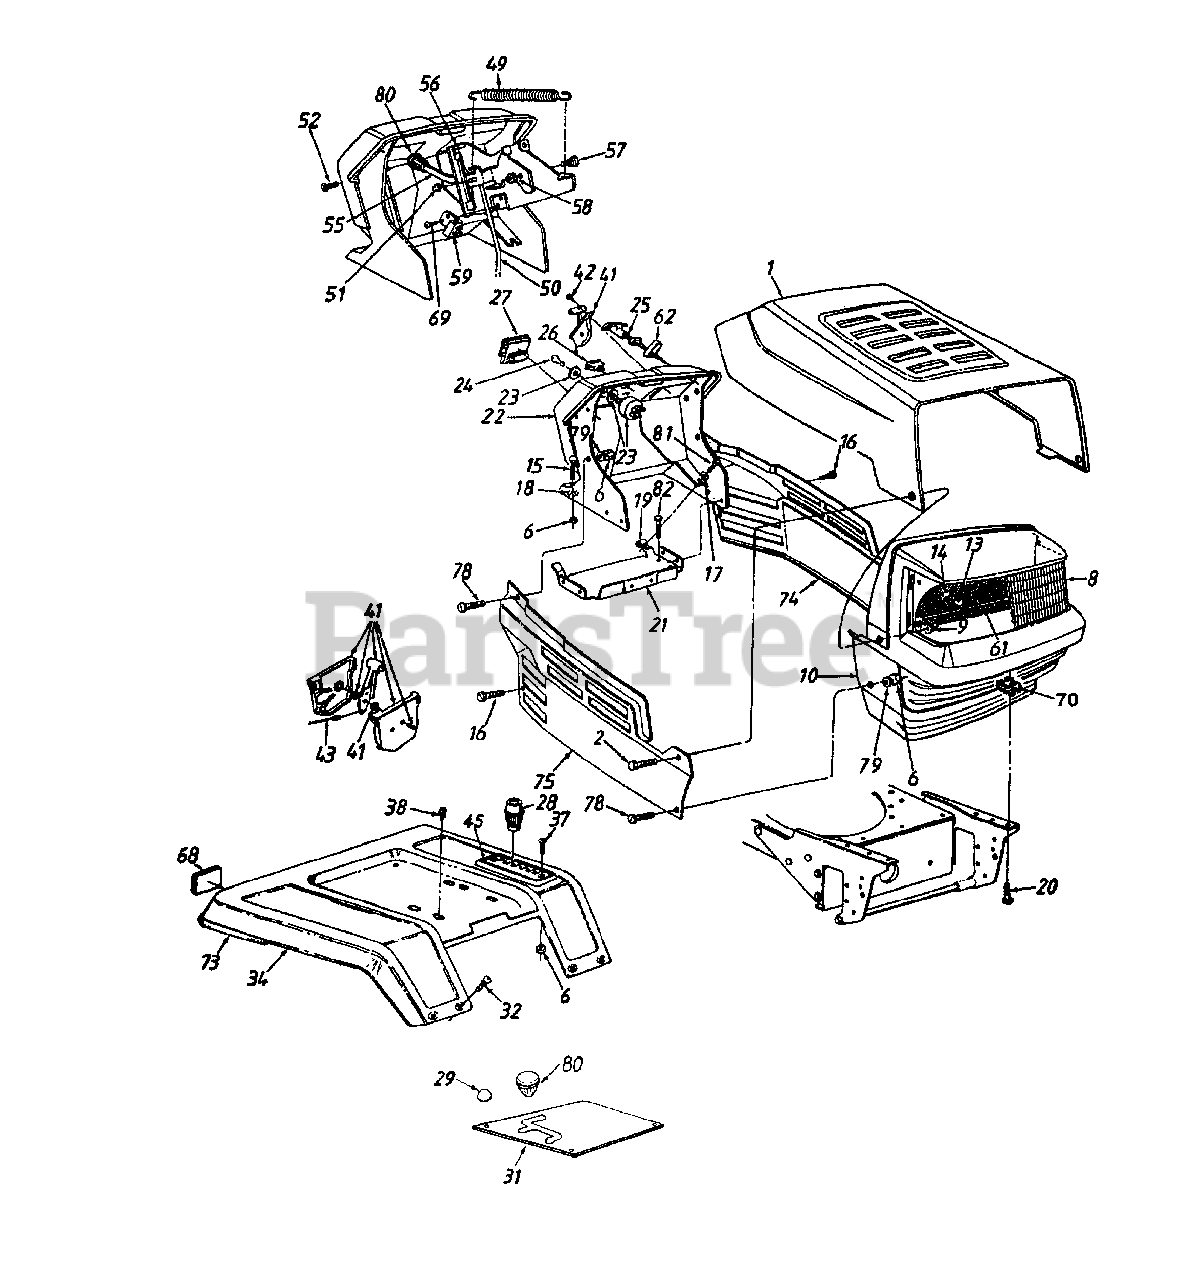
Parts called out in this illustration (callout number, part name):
6	Hex Sems Nut 1/4-20 Thd.
8	Headlight Lens w/Logo
9	Flange L-Nut 1/4-20 Thd.
10	Grille
13	Lamp
14	Socket
15	Carriage Bolt 1/4-20 x 1.0"
16	Hx Wash Hd. TT-Tap Scr. 1 /4-20 x .5" L
17	Fl-Wash. .281" I.D. x .73" O.D.
18	Bolt Retainer 1/4" I.D.
19	Speed Nut 1/4-20 Thd.
20	Hex Bolt 5/16-18 x .75"
23	Ignition Switch
24	Ignition Key
25	Choke Control
27	Ammeter
28	Shift Knob
38	Hx Wash Hd. AB-Tap Scr. 5/16 x .75" L
41	Throttle Box Assembly
42	Truss Mach. AB-Tap Scr. #10 x .5"
43	Throttle Control Wire 35"
45	6-Speed Selector Plate
49	Ext. Spring 5.06"
50	Deck Control Rod
51	Speed Nut 1/4" Rod
52	Torx Mach. Scr. 1/4 x .62"
55	PTO Lever
58	Hex L-Nut 5/16-18 Thd.
59	Safety Switch
61	Grille Reflector Label
62	Retainer Clip
68	Reflector
69	Hx Wash. Hd. B-Tap Scr. #10 x .38"
70	U-Nut 5/16-18 Thd.
73	Trim Strip 81"
79	Bell-Wash. 1/4" I.D.
80	Small Shift Knob
81	Hex TT-Tap Scr. 1/4-20 x .75"
82	Hex AB-Tap Scr. 1/4 x .62"
